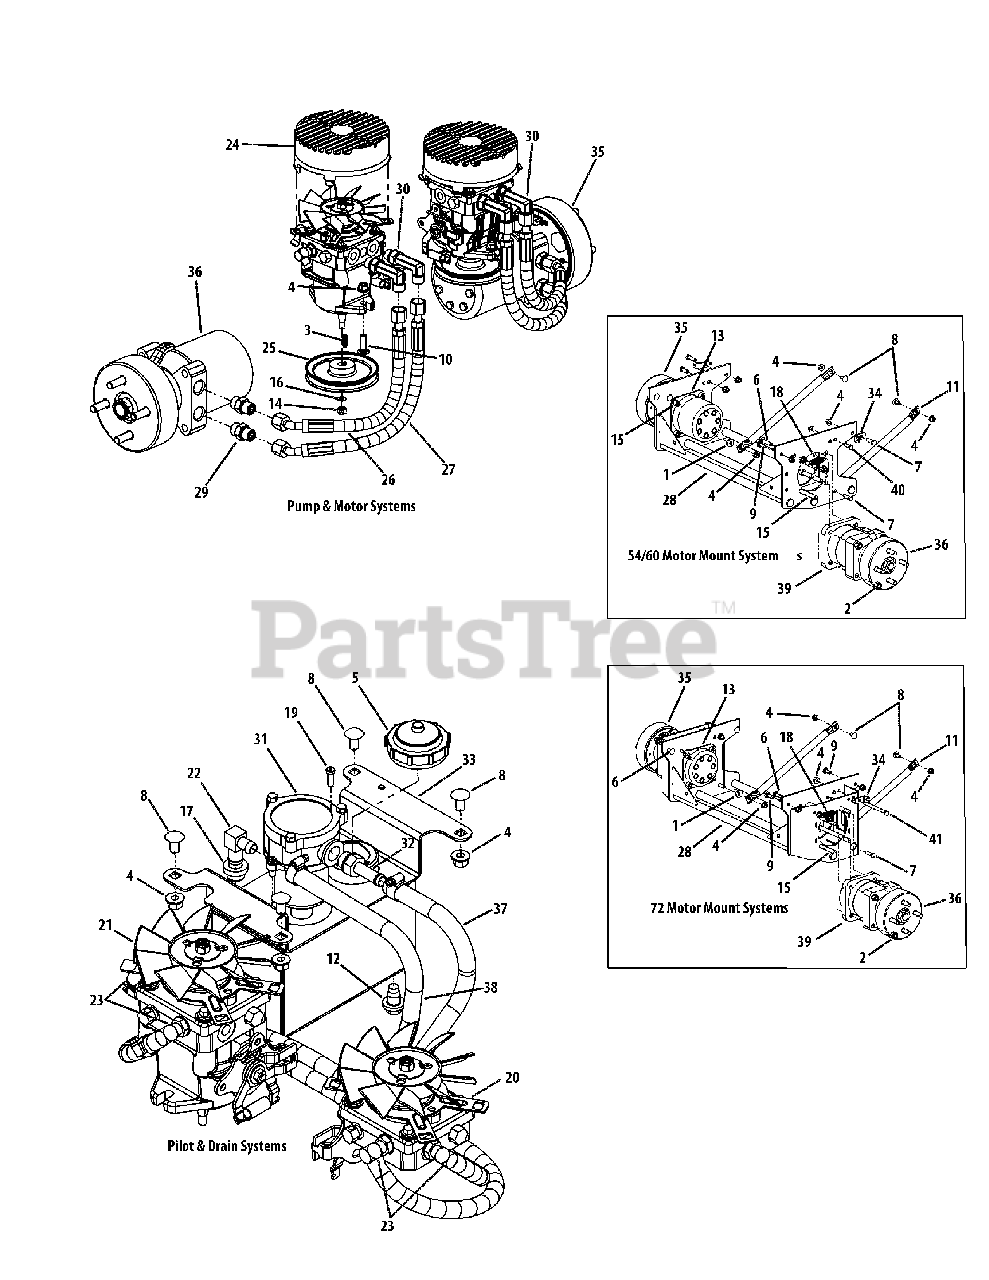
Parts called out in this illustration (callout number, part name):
1	Idler Washer
2	Washer lock 3/8 zinc
3	Key, 3/16" x 7/8"
4	Flange Lock Hex Nut, 3/8-16
5	Cap, Hydro Oil Tank
6	Hex Carriage Screw, 3/8-16, 1.75
6	Hex Carriage Screw, 3/8-16, 5.00 (M72)
7	Hex Cap Screw, 3/8 -16 x 1.25
8	Carriage Bolt, 3/8-16 x .75 LG.
9	Carriage Bolt, 3/8-16 x 1
10	Carriage Screw, 3/8-16 x 1.25
13	Hydro Wheel Motor Backup Plate
14	Hex Nut, 3/8-24
15	Socket Head Cap Screw, 1/2-13; 3-1/2
15	Socket Head Screw, 1/2-13; 6-1/2 (M72)
16	Flat Washer, .469 ID X .875 OD X .105
17	Grommet Fitting, .54 ID x .78 OD
18	Spring Extension, .740 OD x 2.656
19	Head Cap Screw, 1/4-20 x 0.75
20	Hydro Pump, BDP-12, RH
20	Kit, Fan
21	Hydro Pump, BDP-12, LH
21	Kit, Fan
22	Fitting Elbow Spur, 5/8 x 1/2
23	Fitting Elbow, 9/16 x 1/2
24	Fan Pump Shroud
25	Hydro Pump Pulley
26	Short Pressure Hose Assembly
26	Short Pressure Hose Assembly (M72)
27	Long Pressure Hose Assembly
27	Long Pressure Hose Assembly (M72)
29	Adaptor Fitting, 8 x 10
30	Adaptor, 8 x 8
31	Hydraulic In-Tank Filter
32	Replacement Filter
33	Fitting, 3/4 ORB x 1/2 Tube
34	Hydraulic Tank Assembly
35	Rear Cable Mounting Bracket
35	Rear Cable Mounting Bracket (M72)
36	Hydro Motor, LH Assembly
36	Hydro Motor, RH Assembly
37	Hose Assembly, Pilot
37	Tee Fitting, 1/2
37	Hose Clamp, 1/2
37	Fuel Hose, .50 ID x .75 OD
38	Hose Assembly, Drain
38	Tee Fitting, 1/2
38	Hose Clamp, 1/2
38	Fuel Hose, .50 ID x .75 OD
39	Spacer, Hydro, Wheel Motor
40	Hex Cap Screw, 3/8-16 x 1.00
41	Hex Cap Screw, 3/8-16 x 4.50 (M72)
